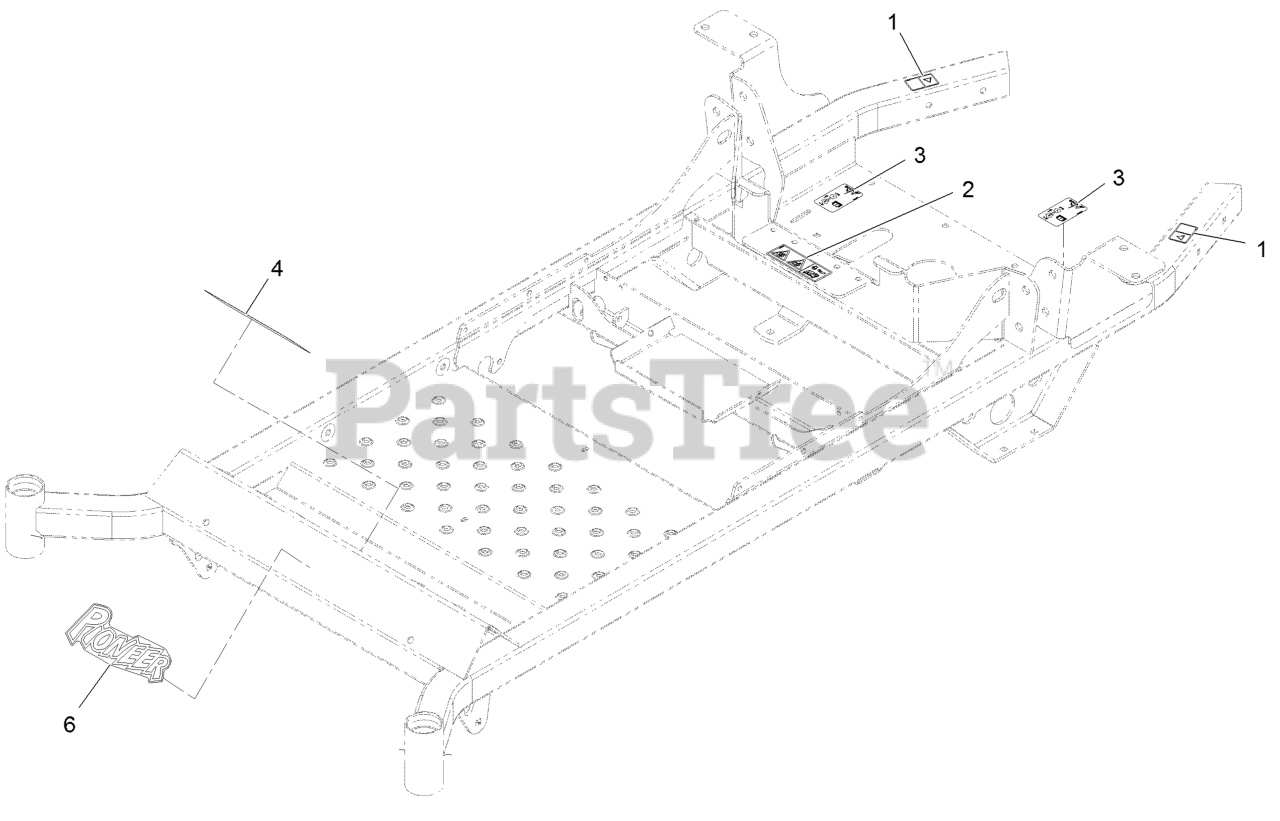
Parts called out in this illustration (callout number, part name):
1	DECAL-WARNING
2	DECAL-WARNING
3	DECAL-RELEASE, DRIVE
4	DECAL-WARNING, SLOPE
6	DECAL-PIONEER LOGO
